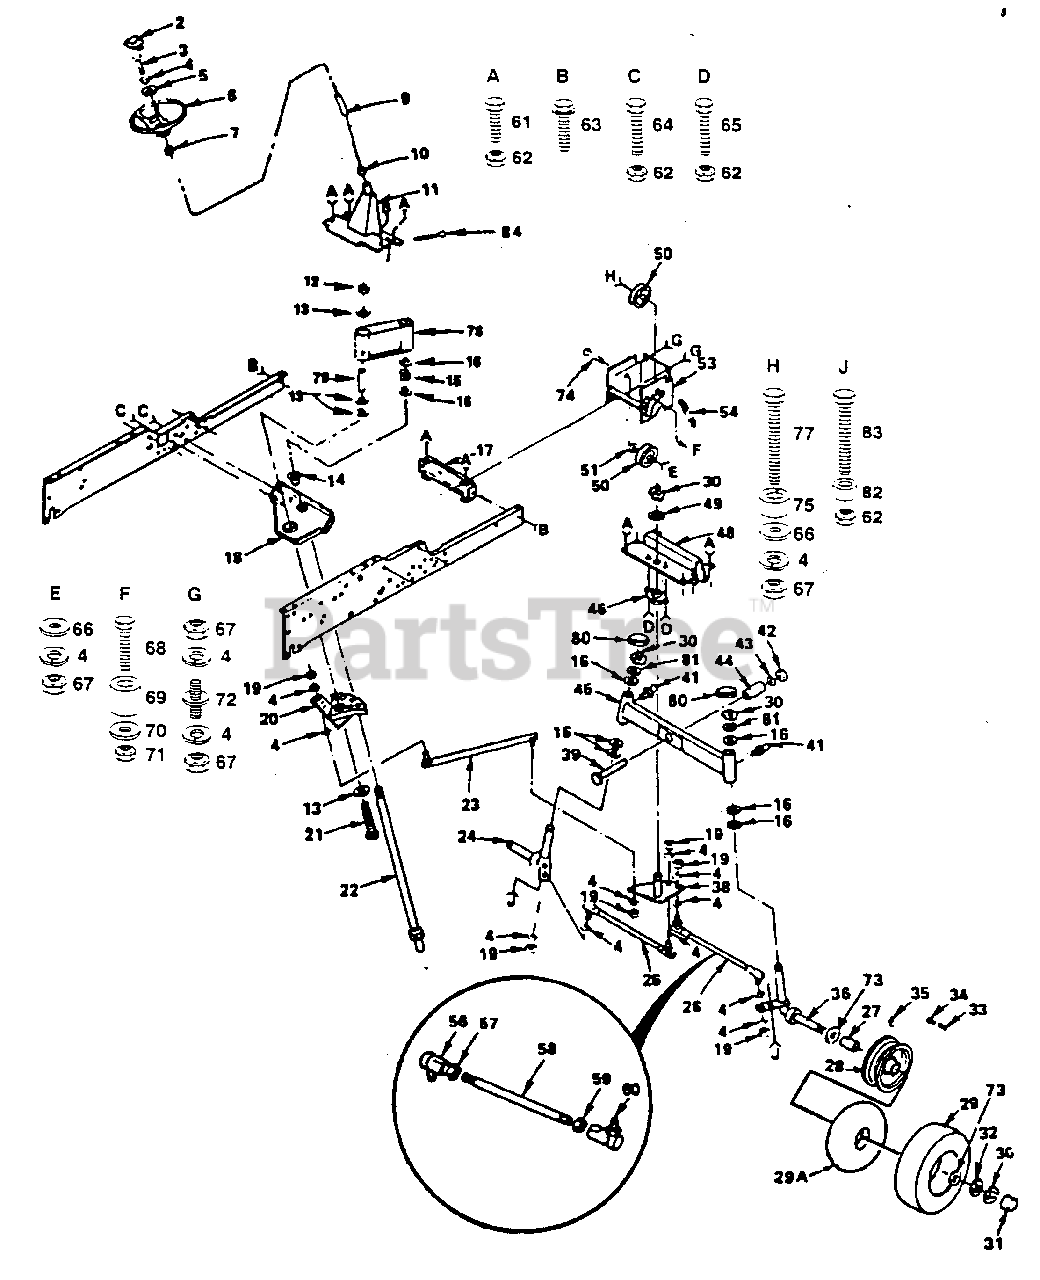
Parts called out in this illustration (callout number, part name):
2	Insert, Steering Wheel (AYP part number)
3	Bolt, Hex 3/8-16 x 1 Gr. 5 (AYP part number)
4	Washer, Lock 3/8 (AYP part number)
5	Washer 13/32 x 2-3/8 x 8 Ga. (AYP part number)
6	Wheel, Steering (AYP part number)
7	Adapter, Steering (AYP part number)
9	Sleeve, Steering (AYP part number)
10	Bearing (AYP part number)
11	Support Assembly, Steering (AYP part number)
12	Locknut 1/2-13 (AYP part number)
13	Washer 17/32 x 1-5/8 x 10 Ga. (AYP part number)
14	Bearing, Flanged (AYP part number)
15	Ring, Klip (AYP part number)
16	Bearing, Thrust (AYP part number)
17	Bracket, Frame Front (AYP part number)
18	Bracket, Support, Steering (AYP part number)
19	Nut, Hex 3/8-24 (AYP part number)
20	Assembly, Sector Gear (AYP part number)
21	Bolt, Hex 1/2-13 x 5 Gr. 5 (AYP part number)
22	Shaft, Steering (AYP part number)
23	Link, Drag (AYP part number)
24	Spindle, L.H. (AYP part number)
26	Rod, Tie Assembly (Inc. Key #56-60) (AYP part number)
27	Bearing (AYP part number)
28	Rim Assembly, Front (AYP part number)
29	Tire (AYP part number)
29A	Tube (AYP part number)
30	Ring, Klip (AYP part number)
31	Cap, Axle, Front (AYP part number)
32	Washer 25/32 x 1-5/8 x 16 Ga. (AYP part number)
33	Cap, Valve (AYP part number)
34	Stem, Valve (AYP part number)
35	Fitting, Grease (AYP part number)
36	Spindle, R.H. (AYP part number)
38	Bellcrank Assembly (AYP part number)
39	Bolt, Hex 5/8-11 x 2-3/4 Gr. 5 (AYP part number)
41	Fitting, Grease (AYP part number)
42	Nut, Hex 5/8-11 (AYP part number)
43	Washer, Lock 5/8 (AYP part number)
44	Tube, Pivot, Axle (AYP part number)
45	Axle Assembly, Front (AYP part number)
46	Bushing, Bellcrank (AYP part number)
48	Bracket, Axle (AYP part number)
49	Washer 29/32 x 1-1/4 x 16 Ga. (AYP part number)
50	Pulley, Idler (AYP part number)
51	Washer 11/32 x 2-3/8 x 8 Ga. (AYP part number)
53	Bracket, Assembly Idler (AYP part number)
54	Spring, Extension (AYP part number)
56	Joint, Tie Rod.Thd., L.H.
57	Nut, Hex Jam 3/8-24 L.H. (AYP part number)
58	Rod, Tie (AYP part number)
59	Nut, Hex Jam 3/8-24 (AYP part number)
60	Joint, Tie Rod, Thd., R. H. (AYP part number)
61	Bolt Hex 3/8-16 x 3/4 (AYP part number)
62	Locknut 3/8-16
63	Screw, Hex, Washer, Thd. Rolling 3/8-16 x 3/4 (AYP part number)
64	Bolt, Hex 3/8-16 x 1 Gr. 5 (AYP part number)
65	Bolt, Hex 3/8-16 x 1 (AYP part number)
66	Washer 11/32 x 7/8 x 13 Ga. (AYP part number)
67	Nut, Hex 3/8-16 (AYP part number)
68	Bolt, Hex 5/16-18 x 1 (AYP part number)
69	Bushing, Handle, Clutch (AYP part number)
70	Washer 11/32 x 7/8 x 16 Ga. (AYP part number)
71	Nut 5/16-18
72	Pin, Mounting, Idler Bracket (AYP part number)
73	Washer 25/32 x 1-1/4 x 16 Ga. (AYP part number)
74	Bolt, Hex 3/8-16 x 2 (AYP part number)
75	Spacer, Split (AYP part number)
76	Collar Weld Assembly (AYP part number)
77	Bolt 3/8-16 x 2-1/4 (AYP part number)
79	Tube (AYP part number)
80	Cover, Dust Cap (AYP part number)
81	Washer 25/32 x 1-5/8 x 16 Ga. (AYP part number)
82	Stop, Spindle (AYP part number)
83	Bolt, Hex 3/8-16 x 2 (AYP part number)
84	Pin, Cotter 1/4-1 (AYP part number)
